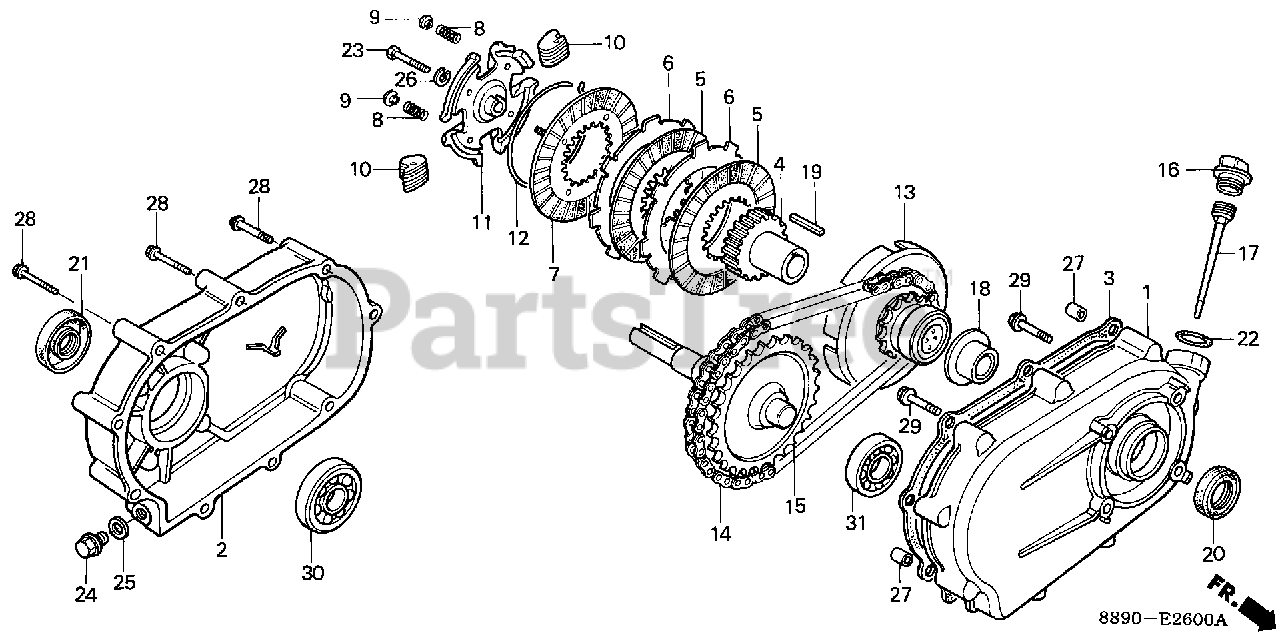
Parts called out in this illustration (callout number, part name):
1	CASE, REDUCTION
2	COVER, REDUCTION
3	GASKET, REDUCTION COVER
4	CENTER, CLUTCH (28T)
5	DISK, CLUTCH FRICTION
6	PLATE, CLUTCH
7	PLATE, CLUTCH PRESSURE
8	SPRING, CLUTCH FREE
9	HOLDER, CLUTCH SPRING
10	WEIGHT, CLUTCH
11	HOLDER, CLUTCH WEIGHT
12	CENTER, CLUTCH WEIGHT
13	SPROCKET, DRIVE (14T)
14	CHAIN, DRIVE (RK428SH-36LE)
15	SHAFT, P.T.O. (28T)
16	CAP, REDUCTION OIL (GRAY)
17	DIPSTICK, OIL
18	WASHER, THRUST (25MM)
19	KEY, CLUTCH CENTER
20	OIL SEAL (30X46X8)
21	OIL SEAL (30X50X7)
21	OIL SEAL (PJ30507)
22	O-RING (26X2.7)
23	BOLT, HEX. (8X35)
24	BOLT, DRAIN PLUG (12MM)
25	WASHER, DRAIN PLUG (12MM)
26	WASHER, SPRING (8MM)
27	PIN, DOWEL (8X14)
28	BOLT, FLANGE (6X50)
29	BOLT, FLANGE (8X32)
30	BEARING, RADIAL BALL (6205)
31	BEARING, RADIAL BALL (6206)
